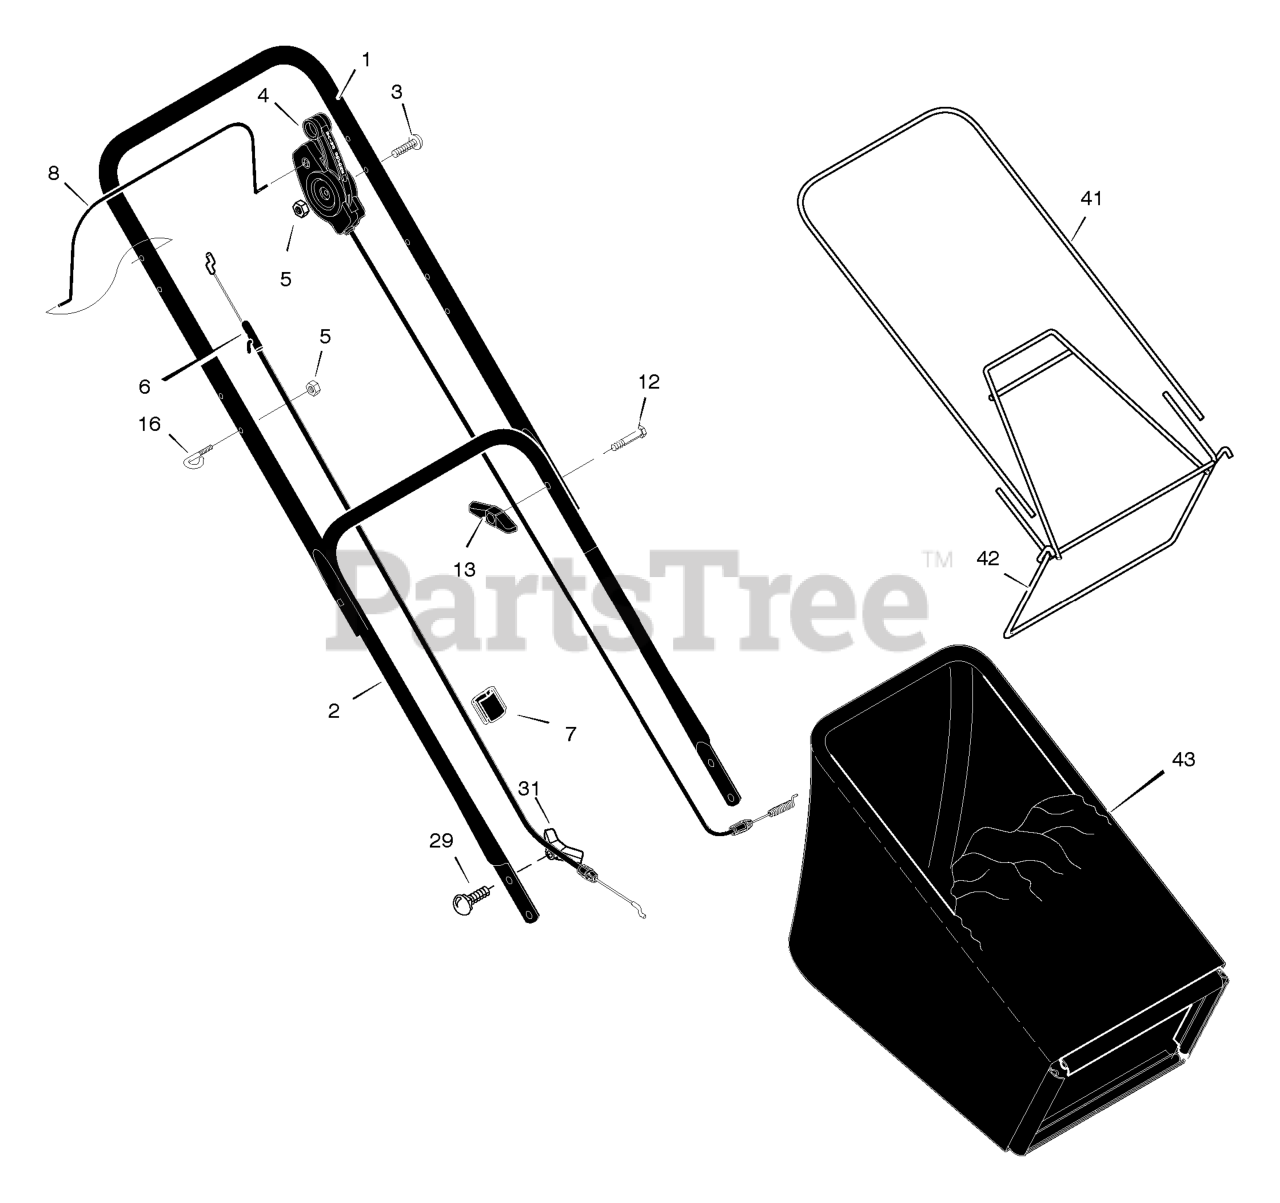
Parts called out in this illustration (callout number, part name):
1	Handle, Upper (Black)
2	Handle, Lower (Black)
4	Control, Drive
5	Locknut
6	Cable, Stop (Briggs)
7	Fastener, Double Cable
8	Lever, Stop
13	Knob
16	Guide, Rope
29	Bolt, Carriage
31	Knob, Plastic
41	Frame, Top
42	Frame Assembly
43	Bag, Cloth
